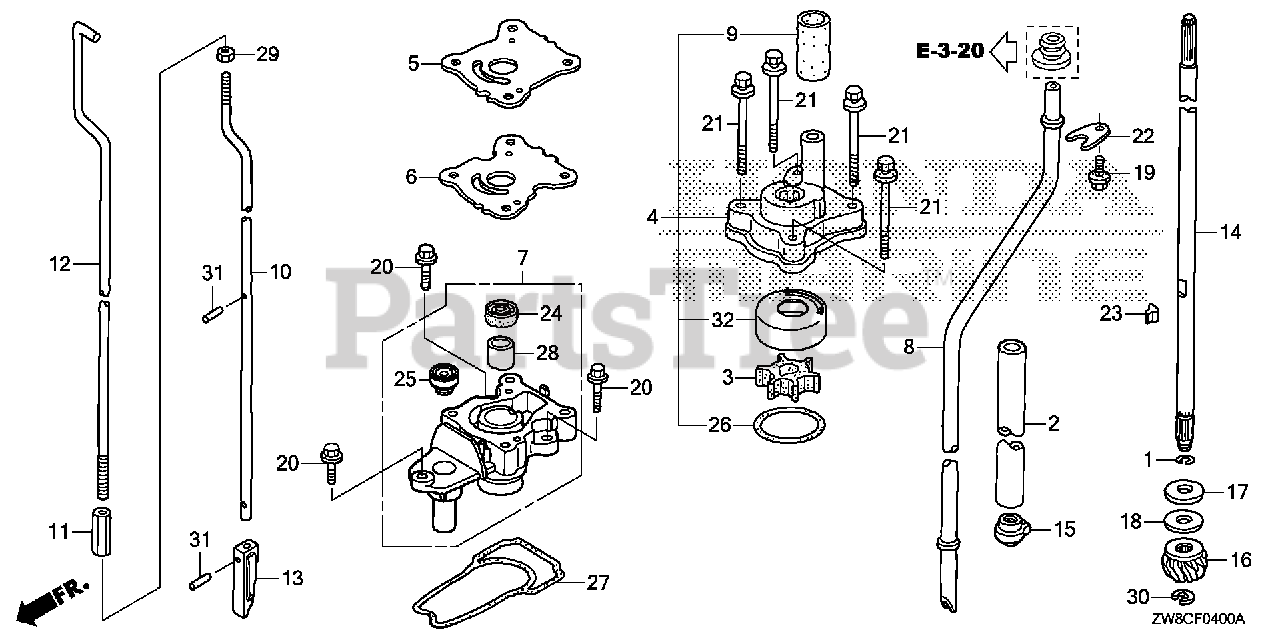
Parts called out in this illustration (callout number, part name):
1	CLIP, VALVE GUIDE
2	GUIDE, OIL (S,L)
3	IMPELLER, PUMP (S,L)
4	HOUSING ASSY., IMPELLER
5	COVER, IMPELLER
6	GASKET, IMPELLER
7	HOUSING, WATER PUMP (S,L)
8	TUBE, WATER (L)
9	RING, WATER TUBE SEAL
10	ROD B, SHIFT (L)
11	JOINT, SHIFT ROD
12	ROD A, SHIFT (L)
13	ROD, PUSH
14	SHAFT, VERTICAL (L)
15	SLINGER, OIL (S,L)
16	GEAR, PINION
17	WASHER A, THRUST BEARING
18	WASHER B, THRUST BEARING
18	WASHER C, THRUST BEARING
19	BOLT, FLANGE (6X12) Use from Frame SN 1005249.
20	BOLT, FLANGE (6X20) (ENGINE NO.)
21	BOLT-WASHER (6X50)
22	PLATE, WATER TUBE SETTING
23	KEY, WOODRUFF
24	SEAL, WATER (13MM) (ARAI)
25	SEAL, WATER (6MM)
26	O-RING (42.2X2.4)
27	O-RING, WATER PUMP HOUSING
28	BUSH (13X15X15)
29	NUT, HEX. (6MM)
30	E-RING (8MM)
31	ROLLER (2.5X11.8)
32	LINER, PUMP
